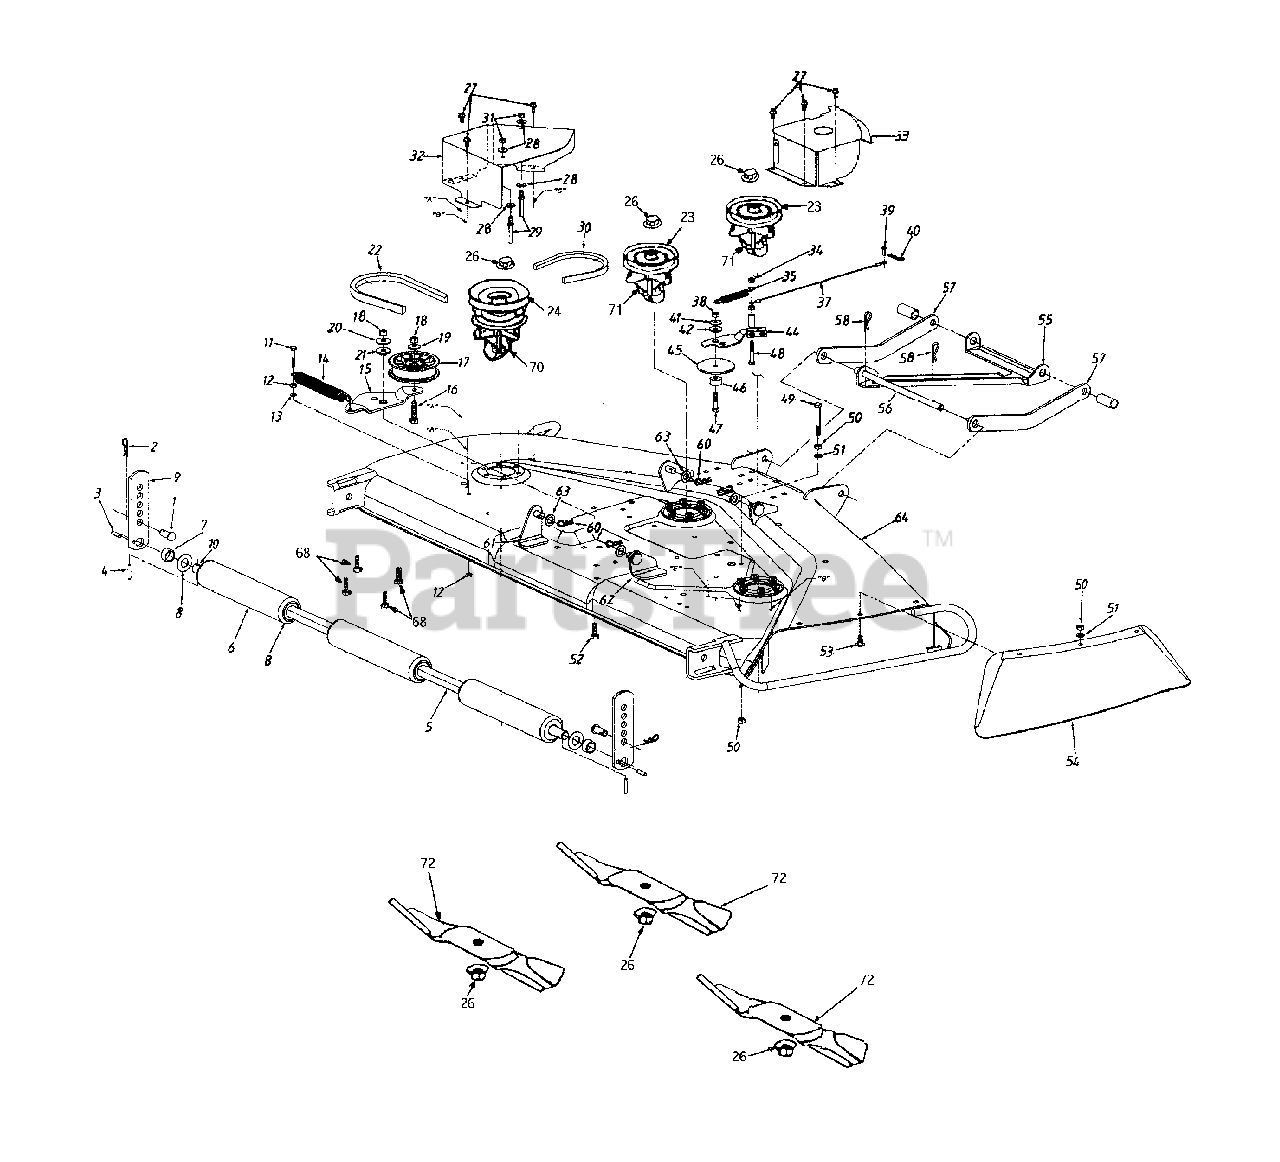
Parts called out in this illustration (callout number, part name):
1	Clevis Pin
2	Hairpin Clip
3	Spring Pin 1/4" x 1" Lg.
4	Spring Pin 3/16" x 1-1/4" Lg.
7	Spacer .75" I.D.
8	Fl-Wash. .76" I.D. x 1.5" O.D.
10	Roller Shaft
11	Hex Bolt 1/4-28 x 1.5" Lg. (Gr. 5)
12	Hex Nut 1/4-28 Thd.
13	L-Wash. 1/4" I.D.
14	Ext. Spring 7.33" Lg.
17	Idler Pulley
18	Hex Nut 3/8-24 Thd.
19	Bell-Wash. 3/8" I.D.
20	Bell-Wash. .39" I.D. x 1.13" O.D.
21	Shld. Spacer.625" I.D.
22	"V"-Belt
23	Deck Pulley
24	Double Deck Pulley
26	Hex Jam Nut 5/8-18 Thd.
27	Hex Wash. Hd. Scr. 1/4-20 x .5" Lg.
28	Bell-Wash. 1/4" I.D.
29	Belt Guard Pin
30	"V"-Belt
31	Hex Nut 1/4-20 Thd.
35	Ext. Spring 3.97" Lg.
37	Brake Cable
38	Hex Nut 5/16-24 Thd.
39	Clevis Pin
40	Hairpin Clip
41	Bell-wash. .325" I.D.
42	Shld. Spacer
44	Brake Ass'y.
45	Fl-Wash. 5/16 I.D.
46	Spacer .44" I.D.
47	Hex Bolt 5/16-24 x 1.5" Lg. (Gr.5)
48	Hex Bolt 1/4-28 x 1.75" Lg. (Gr. 5)
49	Hex Bolt 5/16-18 x 2.5" Lg.
50	Hex Nut 5/16-18 Thd.*
51	L-Wash. 5/16" I.D.*
52	Hex Bolt 3/8-24 x 1" Lg.
53	Carr. Bolt 5/16-18 x .75" Lg.
60	Hairpin Clip
63	Fl-Wash. 1/2" I.D. x .93" O.D.
68	Hex Wash. Hd. Tap Scr.
70	Spindle Ass'y. (L.H.)
71	Spindle Ass'y. (R.H. & Center)
72	Blade
